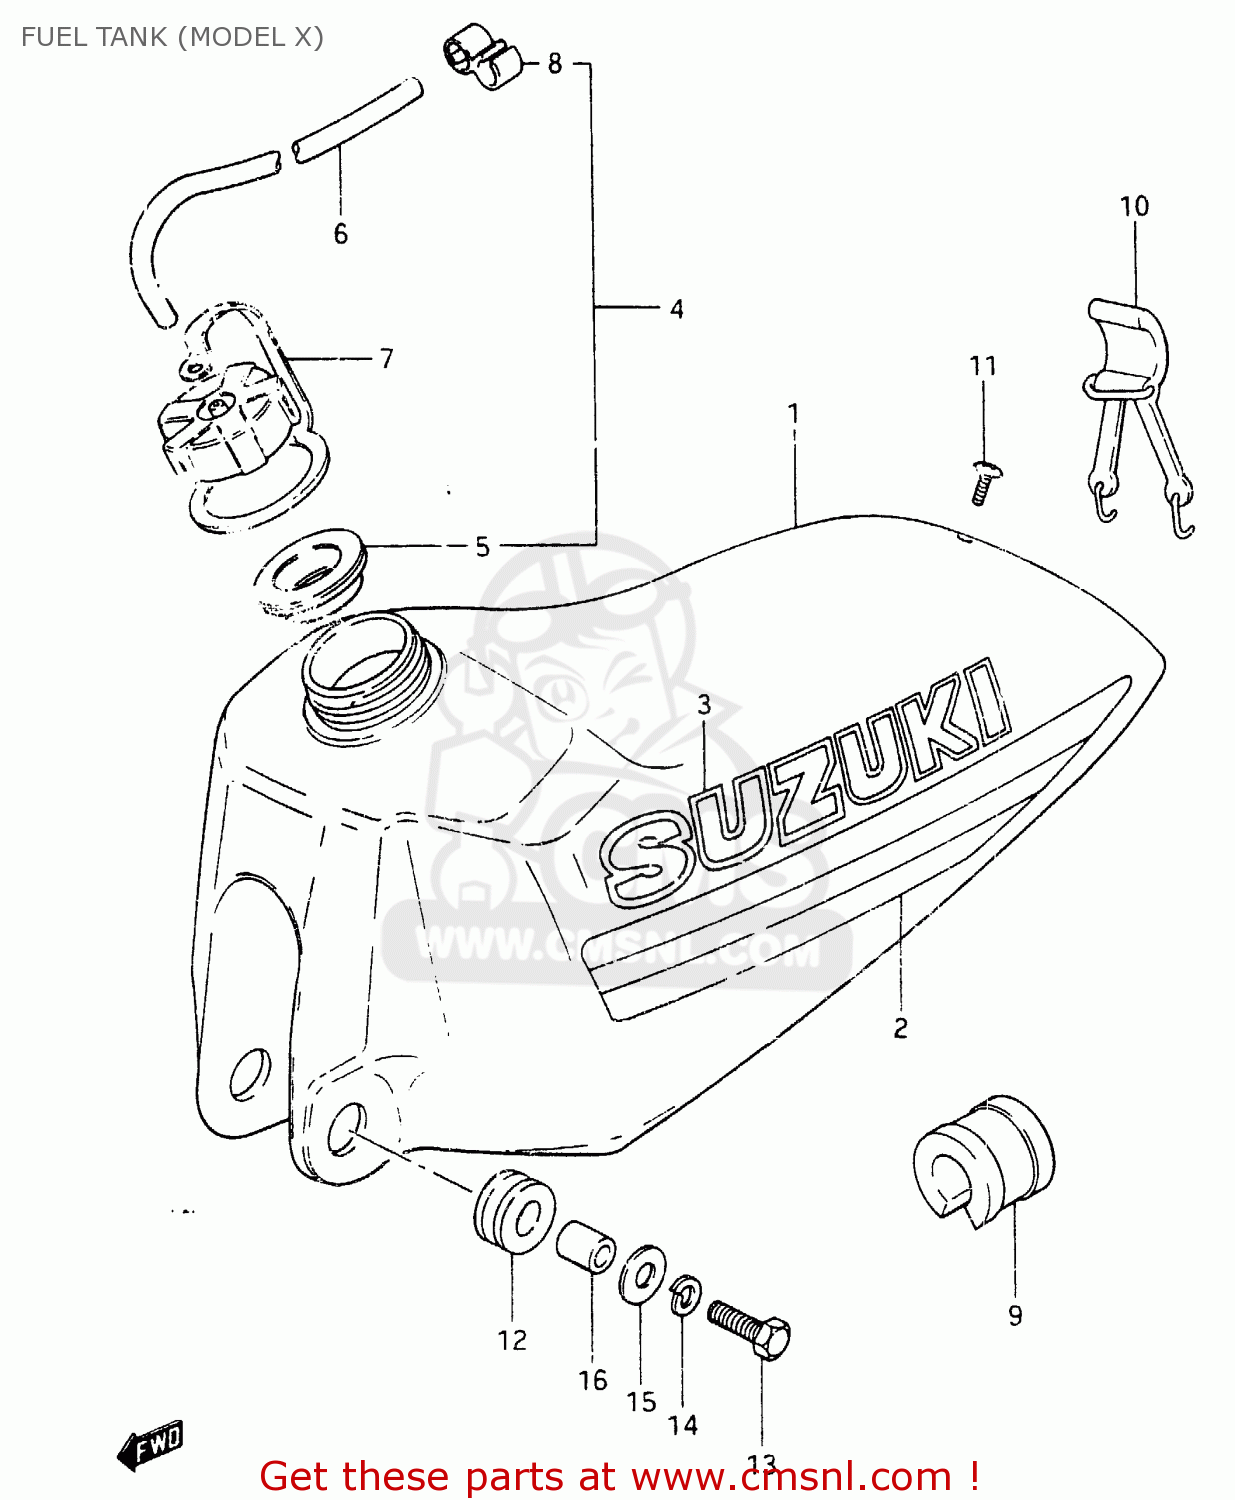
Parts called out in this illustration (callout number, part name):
1	TANK, FUEL (YELLOW)
2	TAPE SET
3	EMBLEM (BLACK)
4	CAP SET,FUEL TANK
5	GASKET,FUEL TANK CAP (NAS)
6	HOSE
7	BAND,FUEL TANK CAP
8	CLAMP,BREATHER HOSE
9	CUSHION,FUEL TANK UPR
10	BAND,FUEL TANK,REAR
11	SCREW (6X15)
12	CUSHION
13	BOLT (8X30)
14	LOCK WASHER
15	WASHER (8.5X29X1.6)
16	SPACER (8.8X12X15.5)
